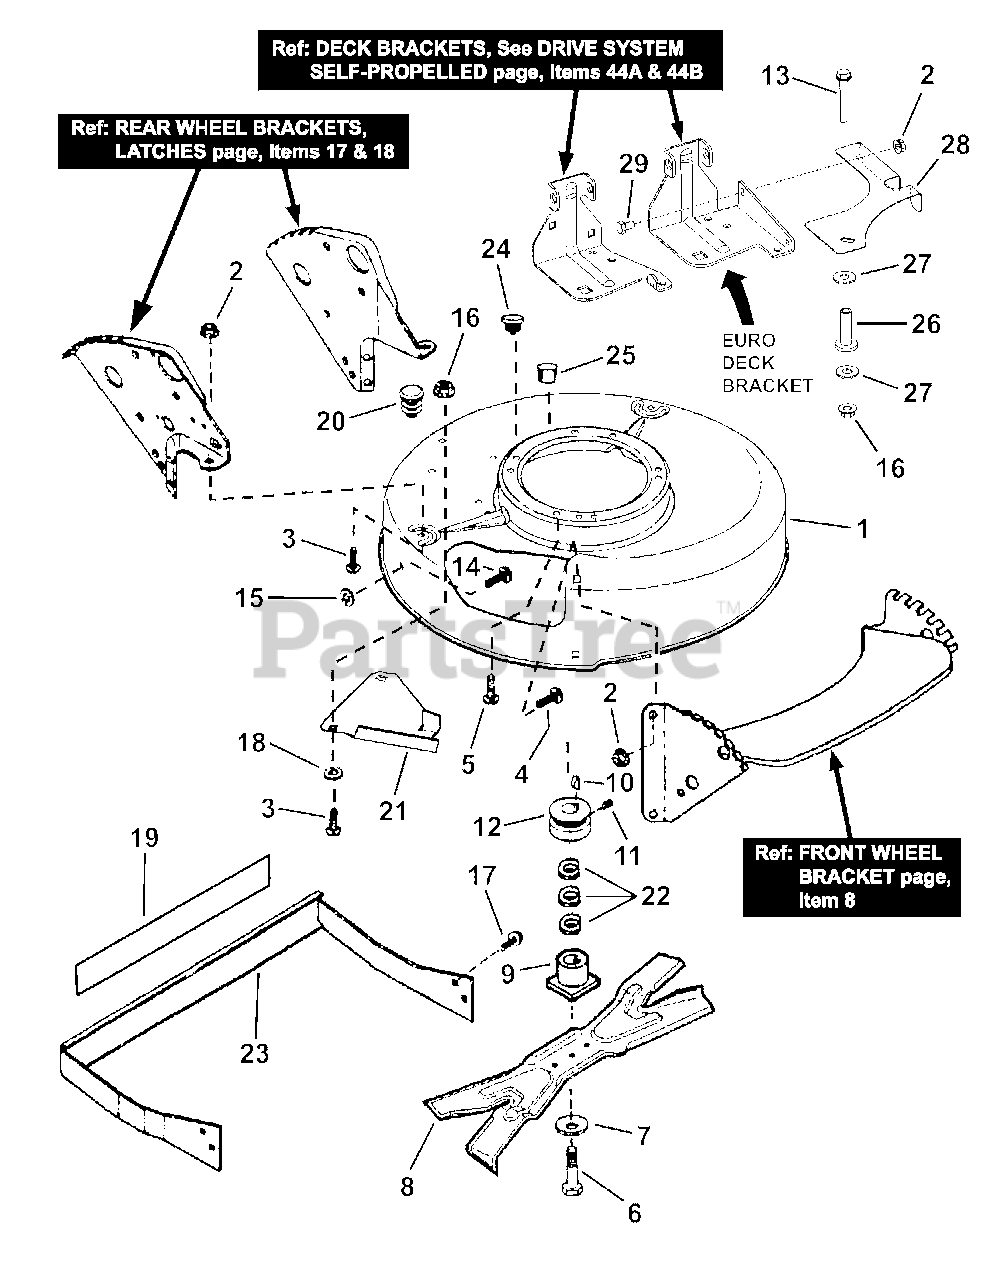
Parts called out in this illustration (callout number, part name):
1	* ASSEMBLY, M Series Push 21" Deck
1	* ASSEMBLY, M Series Propelled, 21" Deck
2	NUT, 5/16-18 Hex Flange Lock, GR5
3	BOLT, 5/16-18 x 1/2" Short Neck Carriage GR5
4	BOLT, 5/16-18 x 1-1/8" Short Neck Carriage GR5
5	SCREW, 3/8-16 x 1" Hex Washer Self-Tap
6	SCREW, 3/8-24 x 2" Hex Head Cap, GR5
7	WASHER, Cone
8	BLADE, 21" Ninja
9	HUB, Blade Drive 25mm
10	KEY, Hi-Pro #HP506 (Briggs engine)
11	SCREW, 5/16-18 x 5/16" Hex Socket Head
12	PULLEY, Engine Drive (25mm x 2-1/8" O.D.)
13	BOLT, 5/16-18 x 2-1/4" Hex Flange Lock
14	BOLT, 5/16-18 x 3/4" Short Neck Carriage GR5
15	RETAINER, 5/16" Bolt
16	NUT, 5/16-18 Hex Large Flange Center Lock
17	SCREW, 1/4-20 x 1/2" Hex Washer Self-Tap
18	WASHER, 7/16" Flat
19	DECAL, Caution, International Symbols
20	HOLE PLUG, Polyethylene
21	COVER, Belt
22	SPACER, .06 Blade Hub
23	FENDER WELDMENT
24	PLUG, 5/16" Square Hole
25	PLUG, 5/16" Round Hole
26	BUSHING, .388 x .625 x 1.62
27	WASHER, 7/16" Flat
28	COVER, Belt- IP21S
29	SCREW, 5/16-18 x 1/2" Hex Head Cap, GR5
